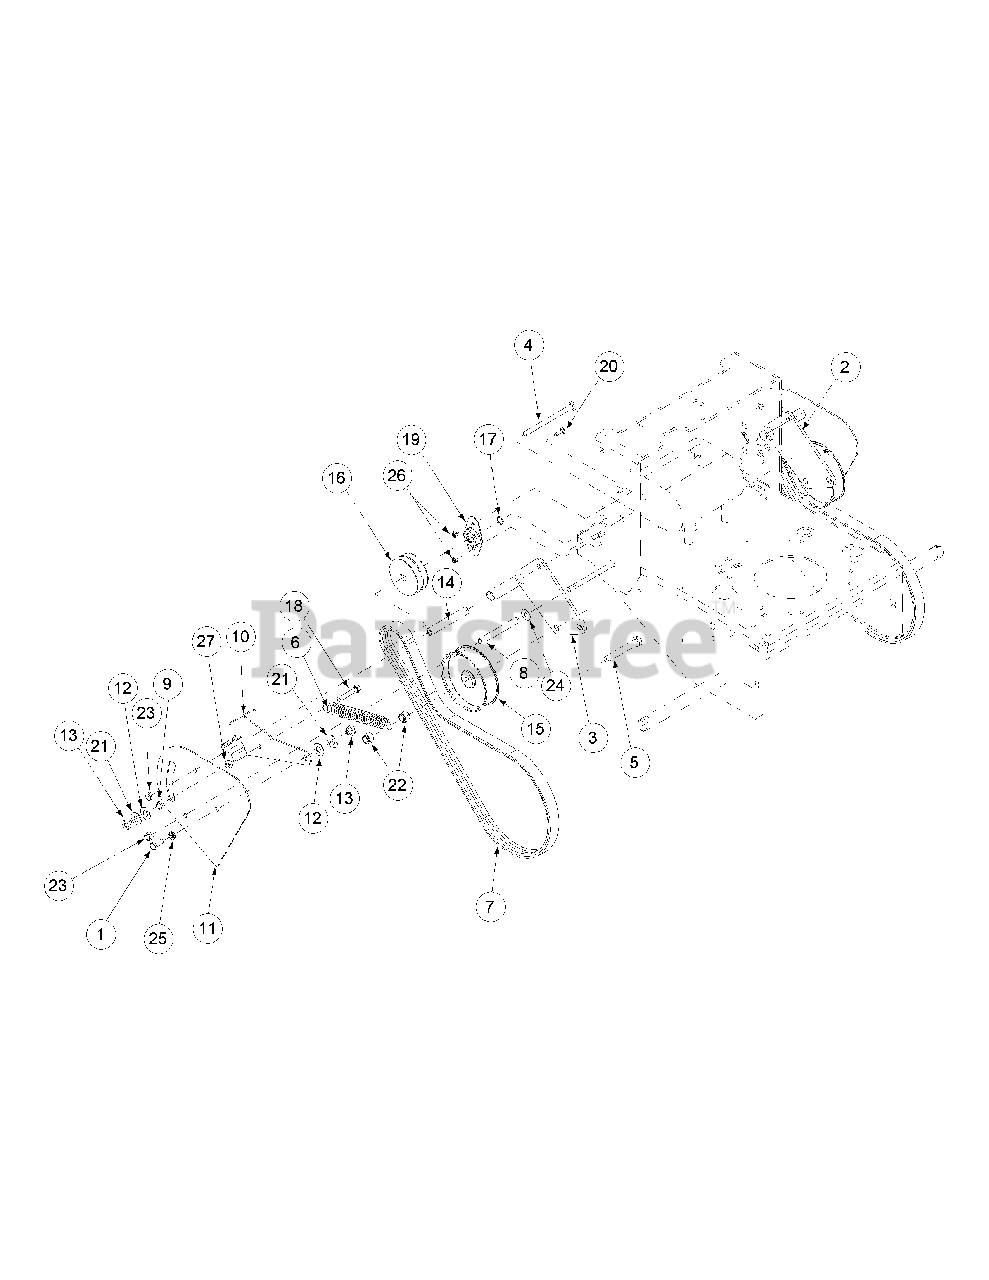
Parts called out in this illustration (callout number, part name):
1	Hex Cap Screw, 3/8-16, .88
2	Left Idler Bracket
3	Right Idler Bracket
4	Carriage Bolt, 3/8-16 x 5.50
5	Hex Cap Screw, 1/2-13, 3.50
6	Extension Spring
8	Spacer Tube
9	Roller Tube
10	Spring Position Adjuster
12	Slide Washer
13	Shoulder Nut
14	Idler Sleeve
15	Flat Idler Drive
16	Jackshaft Pulley
17	External Retain Ring
18	Hex Cap Screw, 3/8-16, 2.00
19	Bearing Housing
20	Carriage Bolt, 1/4-20 x .750
21	Flat Washer, .536 ID x .930 OD x .05
22	Lock Nut, Nylon Insert, 1/2-13
23	Lock Nut, Nylon Insert, 3/8-16
24	Flat Washer
25	Lock Washer, 3/8 Zinc
26	Lock Nut, Nylon Insert, 1/4-20
27	Hex Nut, 3/8-16
